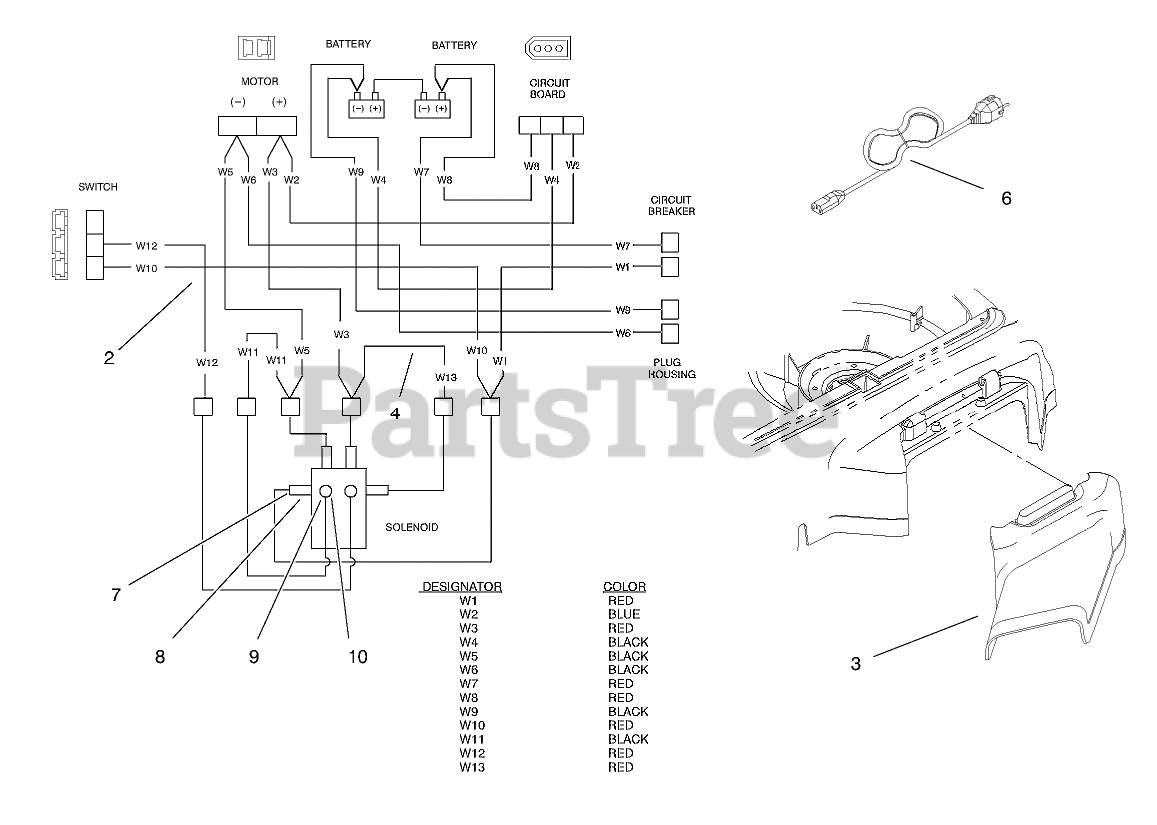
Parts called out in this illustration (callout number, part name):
2	Harness-Wire (Incl. W1-W12)
3	DISCHARGE CHUTE ASM
4	Harness-Wire (Incl. W13)
6	CORD - POWER
7	NUT-JAM
8	WASHER-LOCK
9	NUT-HJ
10	WASHER-LOCK
